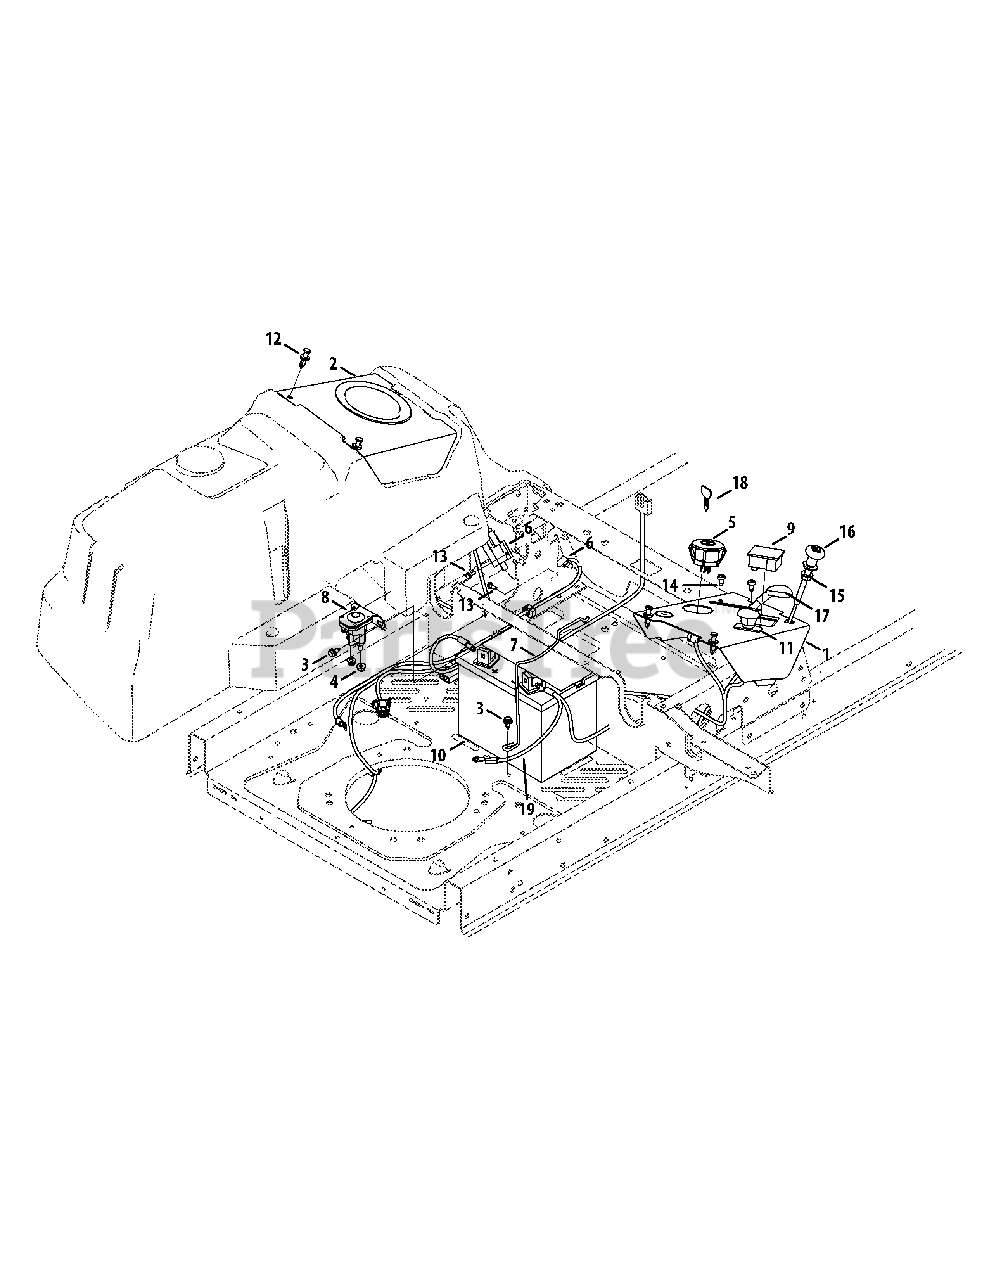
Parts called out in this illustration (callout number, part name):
1	Console Cover, RH
2	Console Cover, LH
3	Hex Washer Screw, 1/4-20 x .625
4	Flange Lock Nut, 1/4-20
5	Key Switch
6	Interlock Switch
7	Battery Rod
8	Solenoid
9	Hour Meter/Service Minder
10	Battery
11	Electric PTO Switch
12	Plastic Rivet
13	Shoulder Screw, #10-32 x .500
14	Screw, 1/4-20 x .50
15	Flange Lock Nut, 3/8-16
16	Choke Cable
17	Throttle Cable
18	Key, Assembly
19	Harness Assembly
